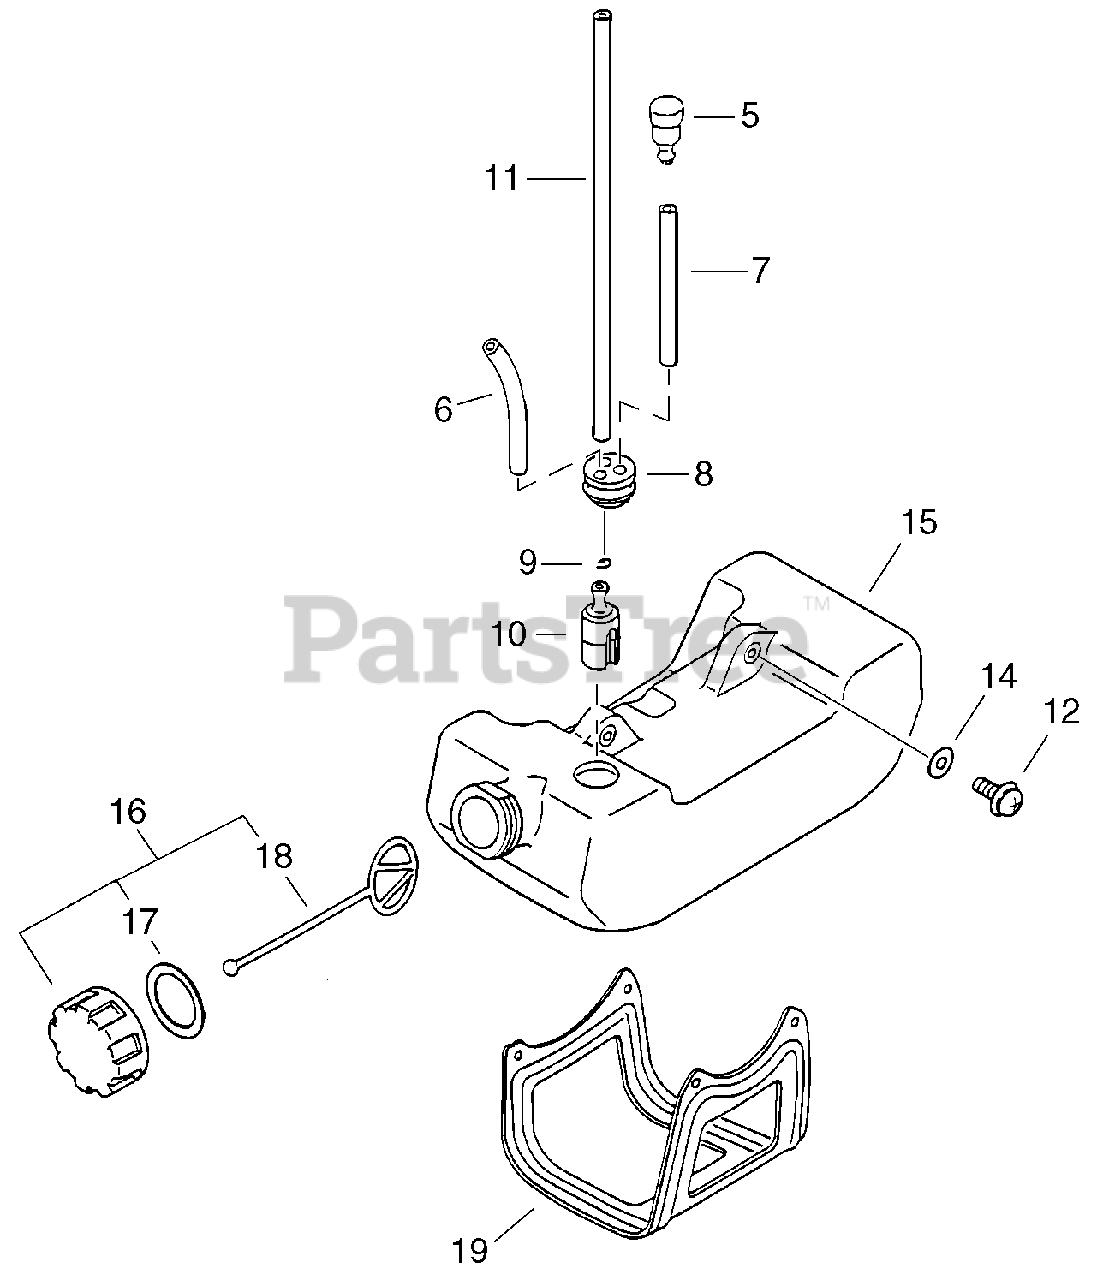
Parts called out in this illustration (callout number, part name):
5	VENT, FUEL TANK
6	PIPE - 3X6X90 -- CLEAR
7	PIPE - 3X5X70 -- BLACK
8	GROMMET
9	CLIP - 6
10	FILTER, FUEL
11	PIPE - 3X5X180 -- BLACK
12	SCREW - 5X16
14	WASHER - 5
15	FUEL TANK ASSY
16	CAP ASSY
17	GASKET, CAP
18	CONNECTOR, CAP
19	GUARD, FUEL TANK
